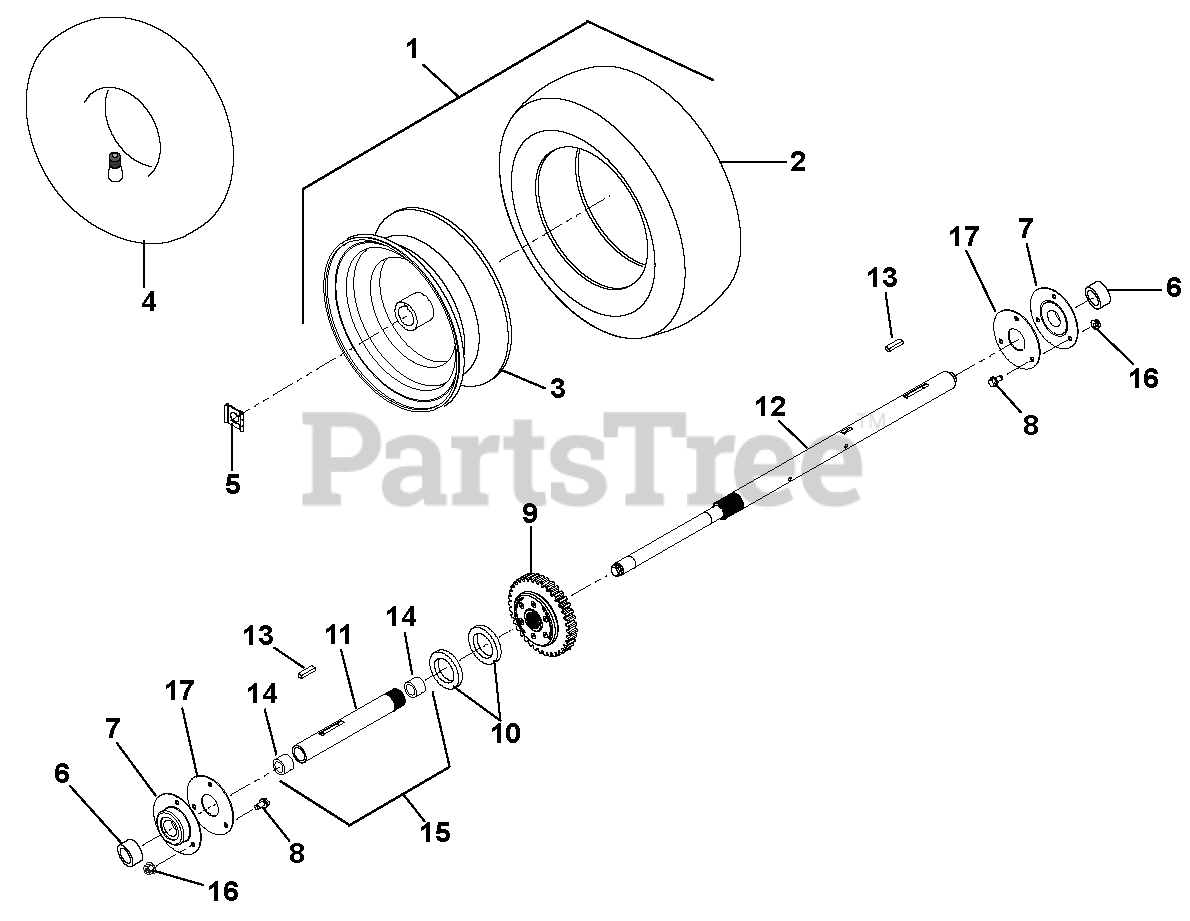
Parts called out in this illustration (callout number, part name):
1	TIRE/WHEEL,RH 16X4.8-8 DIFF T2
2	TIRE, 4.80-8 K478
3	HUB, WHEEL - 16X4.8-8 DIFF
4	TUBE
5	CLIP, SNAP .625 DIA
6	SPACER, PRO AXLE BEARING
7	BRG-FLG 1.003/1.000 3 BOLT
8	@BLT-HEX .25-20X.75 GR5 YWZC
9	DIFFERENTIAL, AUTOMATIC
10	WSHR-FL-STL- 1.062X2.0X.134 YZ
11	AXLE, SHORT-PRO AUTO DIFF
12	AXLE, LONG-PRO AUTO DIFF
13	KEY-RECT .25X.188X1.00
14	BSHG-SLV .706X.764X.75 BRZ
15	AXLE, SHORT-AUTO W/BUSHINGS
16	@NUT-LK-TOP-FLG .25-20 YWZC
17	PLATE, BEARING SPACER
